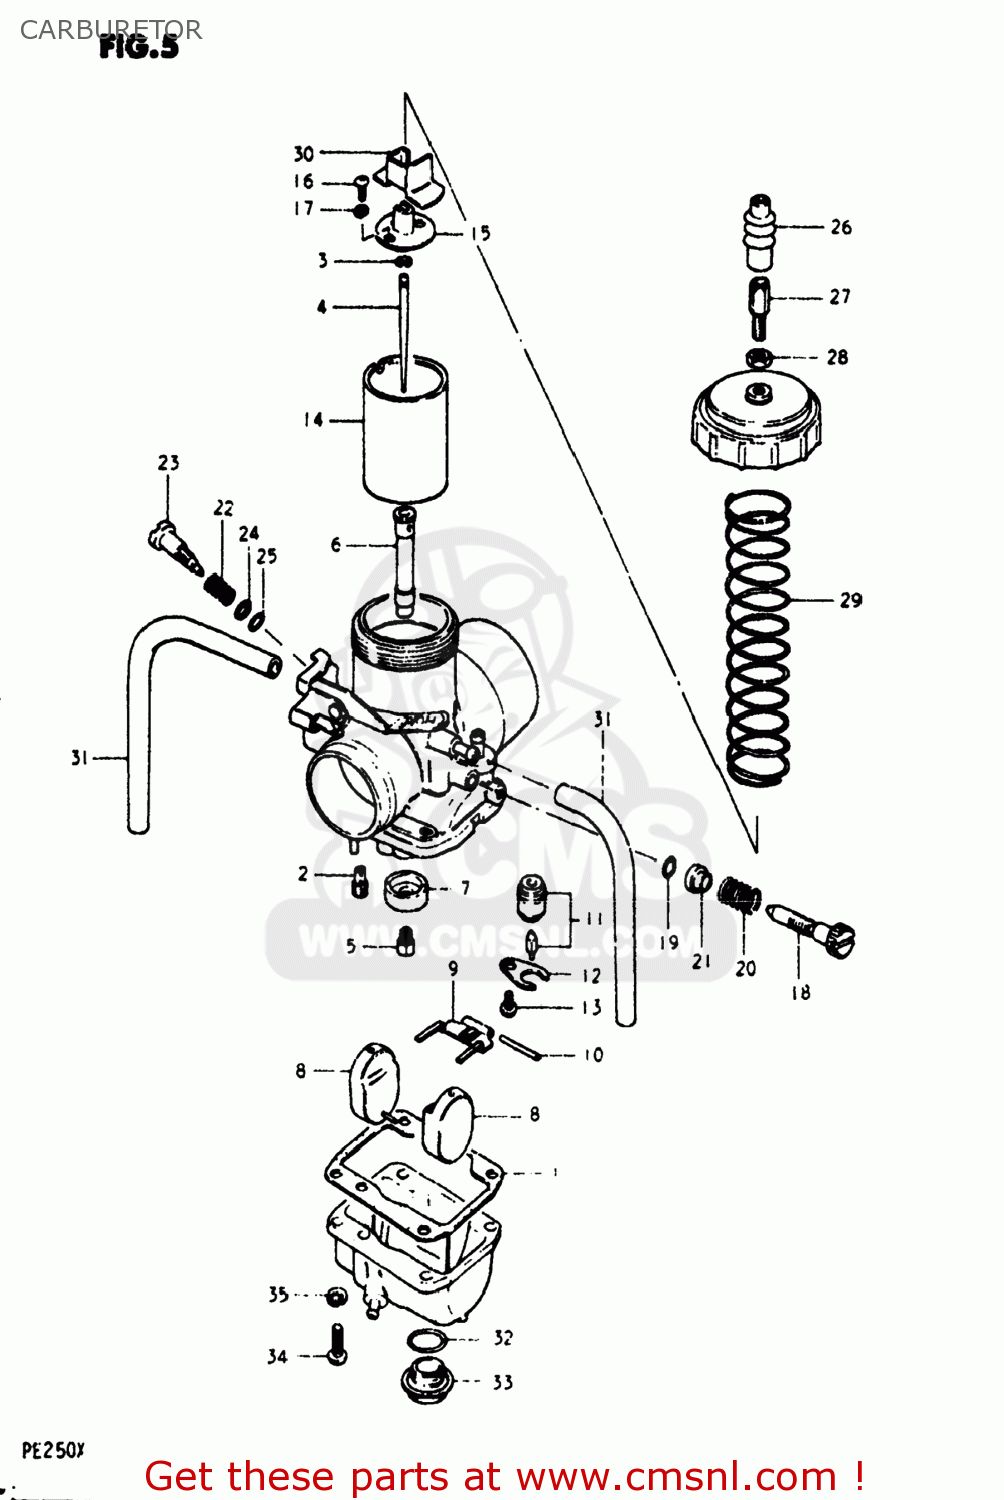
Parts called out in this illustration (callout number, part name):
0	CARBURETOR ASSEMBLY
1	GASKET,FLOAT CAHMBER (NAS)
2	JET,PILOT
3	CLIP
4	NEEDLE JET
5	JET
6	JET,NEEDLE
7	RING,MAIN JET FIXING
8	FLOAT
9	ARM,FLOAT
10	PIN,FLOAT
11	VALVE ASSEMBLY,NEEDLE
12	PLATE
13	SCREW
14	VALVE,THROTTLE
15	CONNECTOR
16	SCREW
17	LOCK WASHER
18	SCREW,THROTTLE STOP
19	O-RING
20	SPRING,THROTTLE STOP
21	COVER
22	SPRING
23	SCREW,PILOT AIR
24	WASHER,PILOT AIR SCREW
25	O RING
26	CAP,CABLE ADJUSTER
27	ADJUSTER,CABLE
28	NUT
29	SPRING,THROTTLE VALVE RETURN
30	COVER,HOLDER
31	HOSE
32	O-RING
33	PLUG
34	SCREW
35	LOCK WASHER
36	JET
